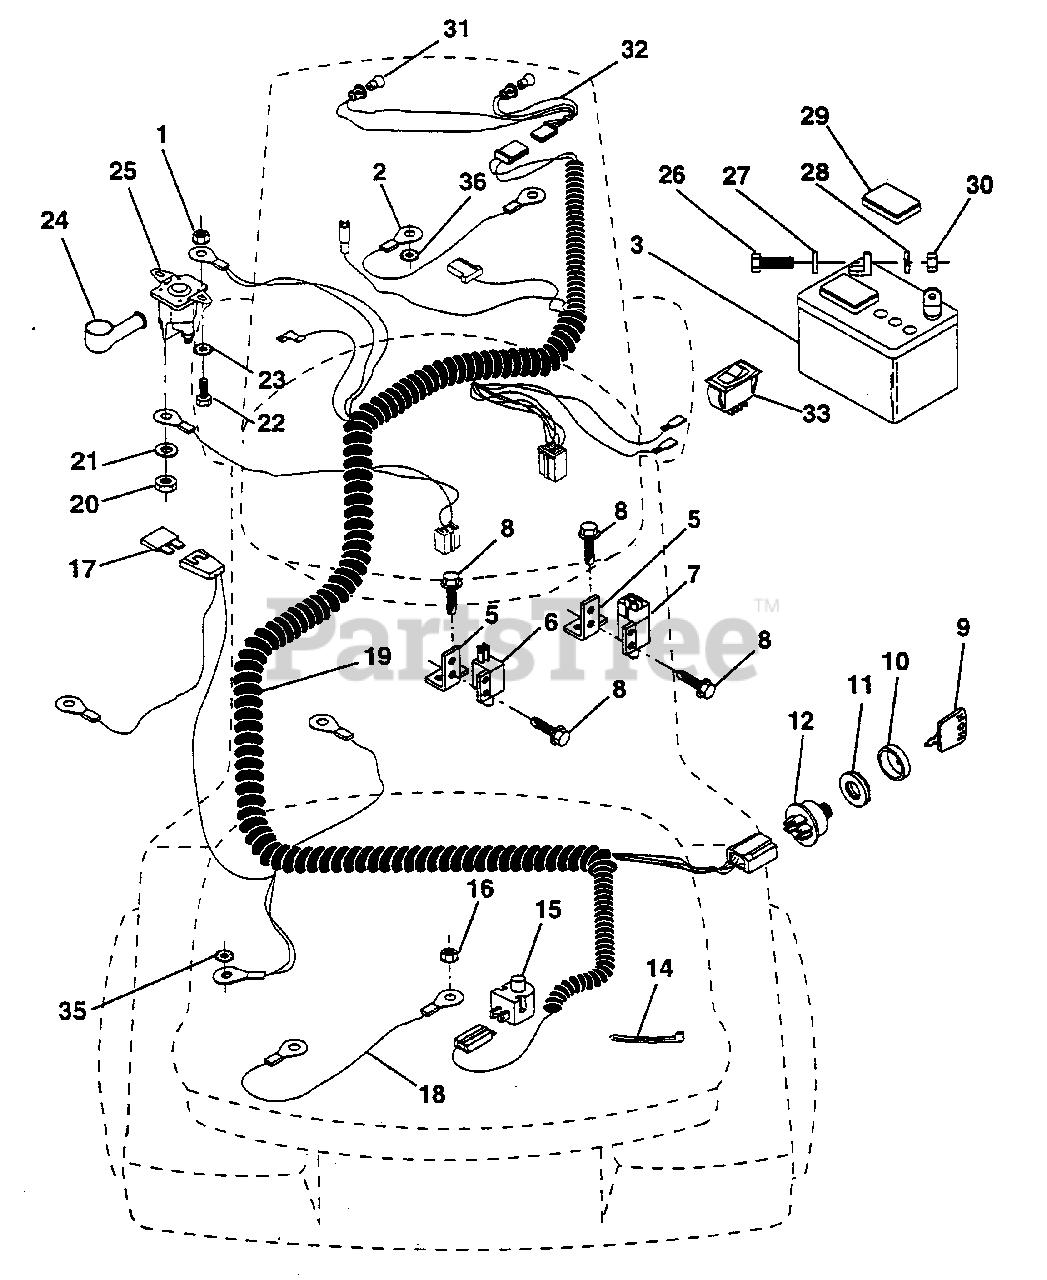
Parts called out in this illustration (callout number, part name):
1	Nut, Hex, Keps 1/4-20 (AYP part number)
2	Assembly, Cable (AYP part number)
3	Battery (AYP part number)
5	Bracket, Switch (AYP part number)
6	Switch, Interlock, 2 Terminal (AYP part number)
7	Switch, Interlock, 4 Terminal (AYP part number)
8	Screw, Hex Head, Self-Tapping #10-24 x 1/2 (AYP part number)
9	Key, Molded (AYP part number)
10	Cover, Ignition Key (AYP part number)
11	Nut, Ignition (AYP part number)
12	Switch, Ignition (AYP part number)
14	Tie, Cable (AYP part number)
15	Switch, Plunger (AYP part number)
16	Nut, Hex, Keps 5/16-18 (AYP part number)
17	Fuse (AYP part number)
18	Assembly, Cable (AYP part number)
19	Harness, Ignition
20	Nut, Hex, Jam 1/4-20 (AYP part number)
21	Washer, Lock 1/4 (AYP part number)
22	Bolt, Hex Head, Fin. 1/4-20 UNC x 1/2 Grade 5 (AYP part number)
23	Washer, Lock, External Tooth 1/4 (AYP part number)
24	Cover, Terminal (AYP part number)
25	Solenoid (AYP part number)
26	Bolt, Hex Head 1/4-20 UNC x 3/4 (AYP part number)
27	Washer 9/32 x 5/8 x 16 (AYP part number)
28	Washer, Lock 1/4 (AYP part number)
29	Cap, Battery (AYP part number)
30	Nut, Hex, Fin. 1/4-20 UNC (AYP part number)
31	Bulb, Light (AYP part number)
32	Socket, Light Harness (Includes Key Number 31) (AYP part number)
33	Switch, Light (AYP part number)
35	Washer, Lock, External Tooth 3/8 (AYP part number)
36	Washer, Lock, Internal Tooth 1/4 (AYP part number)
